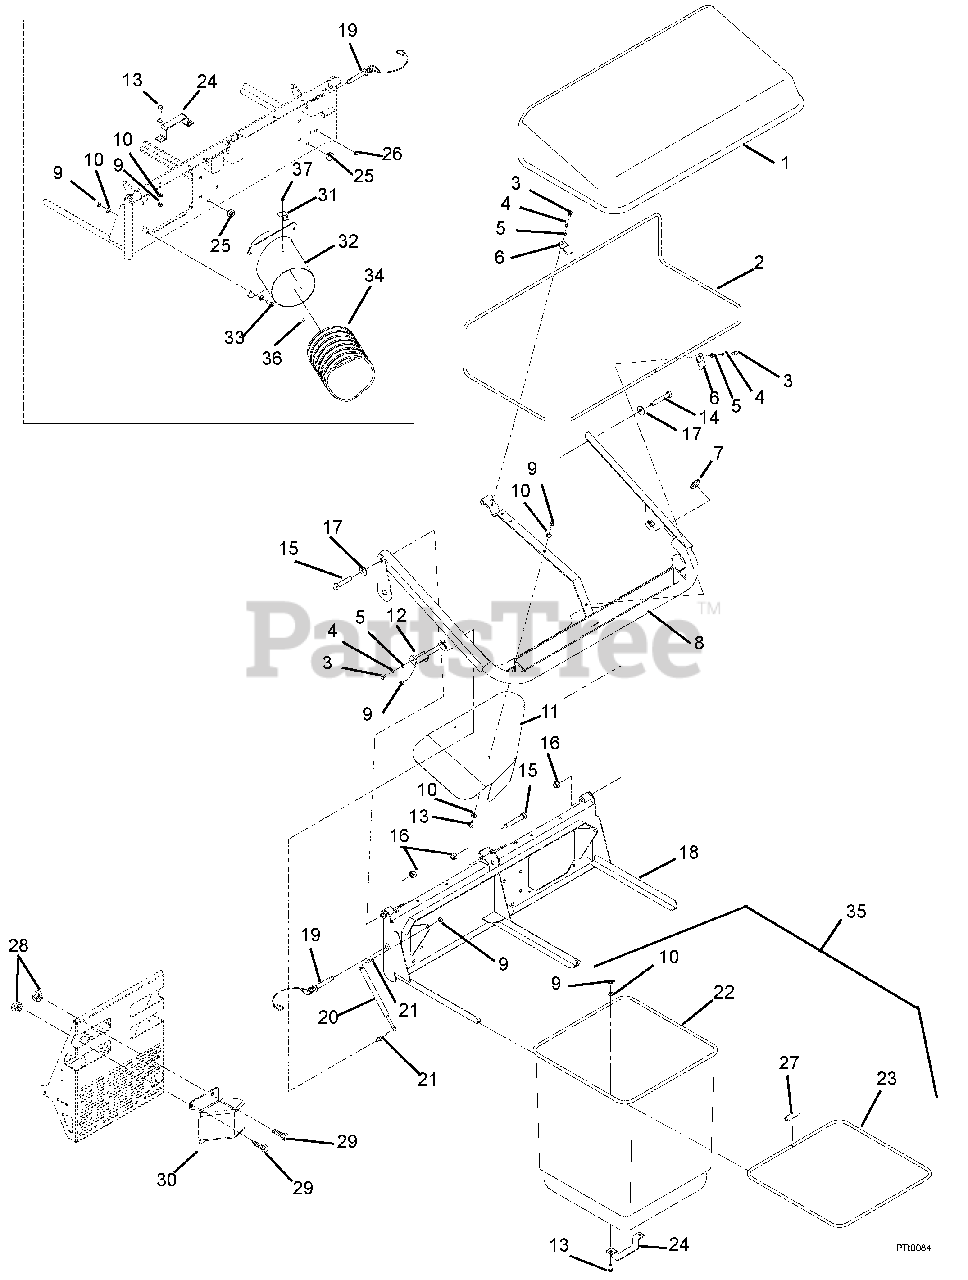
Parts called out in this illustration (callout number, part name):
1	2-Bag Fabric Cover W/J-Strip
2	Air Dome Frame .38 Rod
3	Bolt, Hex .25-20 x .75 Grade 5
4	Washer, Locking .25 x .062
5	Washer, Flat Steel .281 x .62 x .065
6	Bracket, Mount Single Hole
7	Hole Plug, Round
8	Cap Support
9	Nut, .31-18 Nyloc Flange
10	Washer, Flat, Steel .344 x .688 x .065
11	2-Bag Deflector
12	Bracket, Gas Cylinder Mount
13	Bolt, Hex .31-18 x .75 Grade 5
14	Bolt, Hex .50-13 x 2.50 Grade 5
15	Bolt, Hex .50-13 x 3.00 Grade 5
16	Nut, Locking-Nylon .50-13
17	Washer, Flat-Steel .531 x 1.06 x .095 YWZC
18	2-Bag Support Mount
19	Detent Pin W/Lanyard 1/2 x 2-.50
20	Gas Cylinder
21	Ball Stud
22	Cloth Bag
23	Grass Bag Frame
24	Bag Handle
25	Rubber Bumper
26	Hole Plug 7/16
27	Tube Connector
28	Nut, Locking Center .25-20
29	Bolt, Hex .25-20 x .50 Grade 5
30	Deflector, Exhaust
31	Thumb Latch, A-10 Quick Release
32	Inlet Adapter 100 Series
33	Bolt, Hex .31-18 x 1.00 Grade 5
34	Hose, 7 x 45 Goodyear
35	Bag Assembly
36	Screw, Machine 10-24 x .50 Hex Washer Head
37	Nut, Locking Nylon 10-24 with Insert
